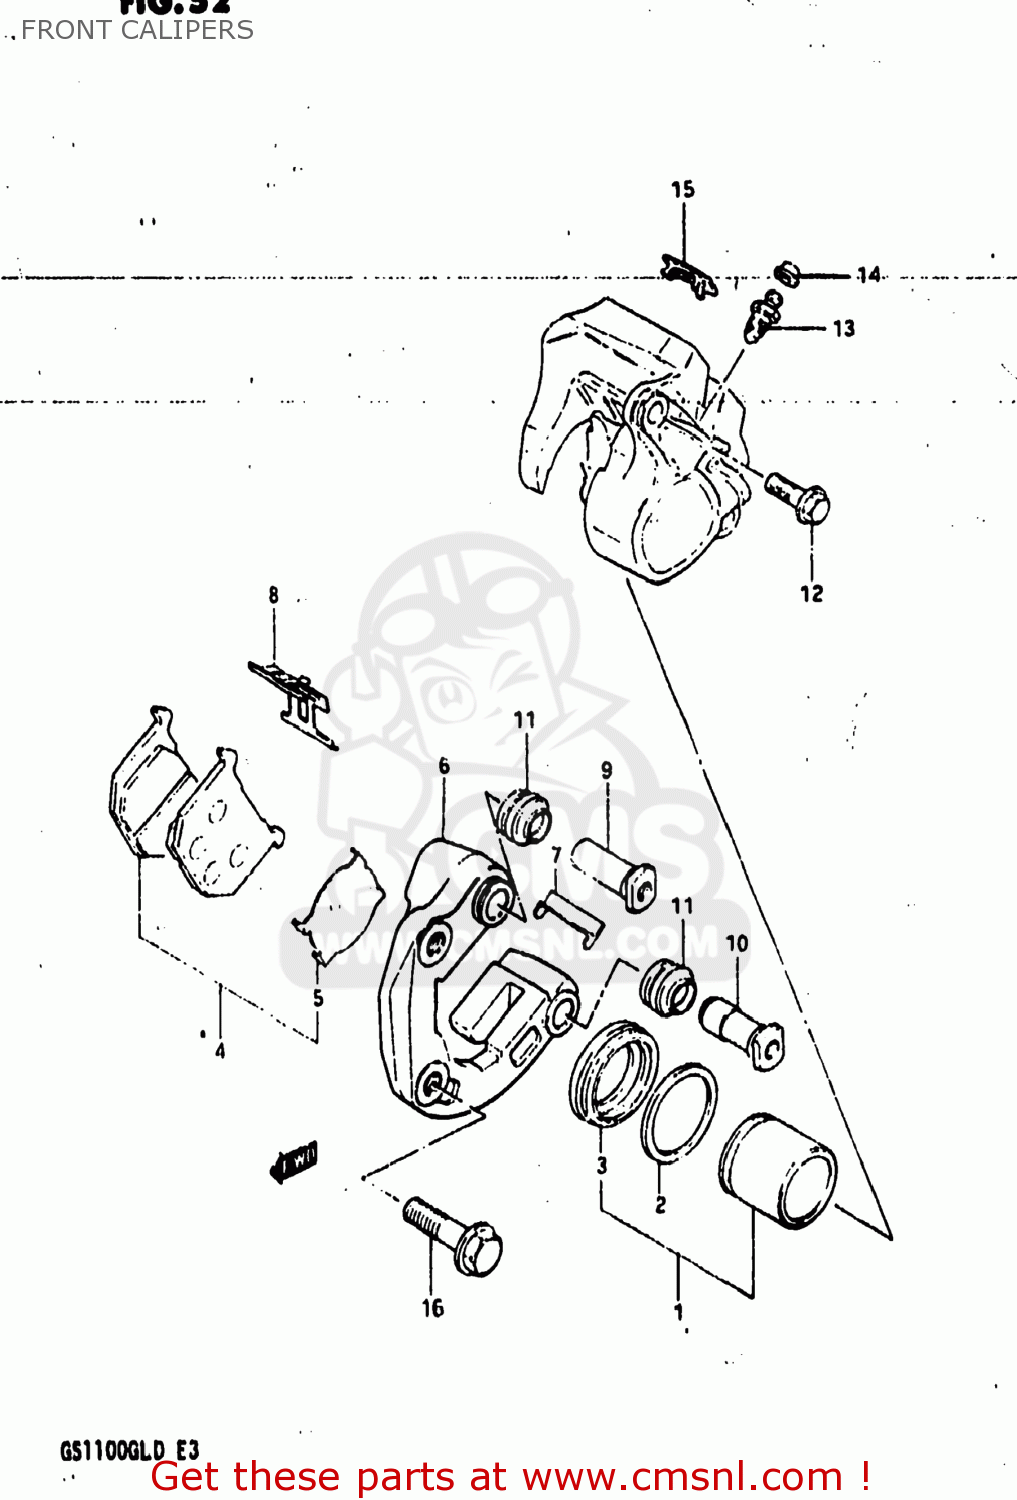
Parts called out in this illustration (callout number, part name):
0	CALIPER ASSEMBLY,FRONT,LEFT
1	PISTON SET
2	SEAL,PISTON
3	BOOT,PISTON
4	PAD SET,BRAKE (MCA)
5	SHIM,PAD
6	CARRIER,CALIPER
7	GUIDE,PAD
8	SPRING,PAD
9	AXLE NO.1
10	AXLE NO.2
11	BOOT,AXLE
12	BOLT
13	BLEEDER
14	CAP,BREATHER
15	COVER
16	BOLT
